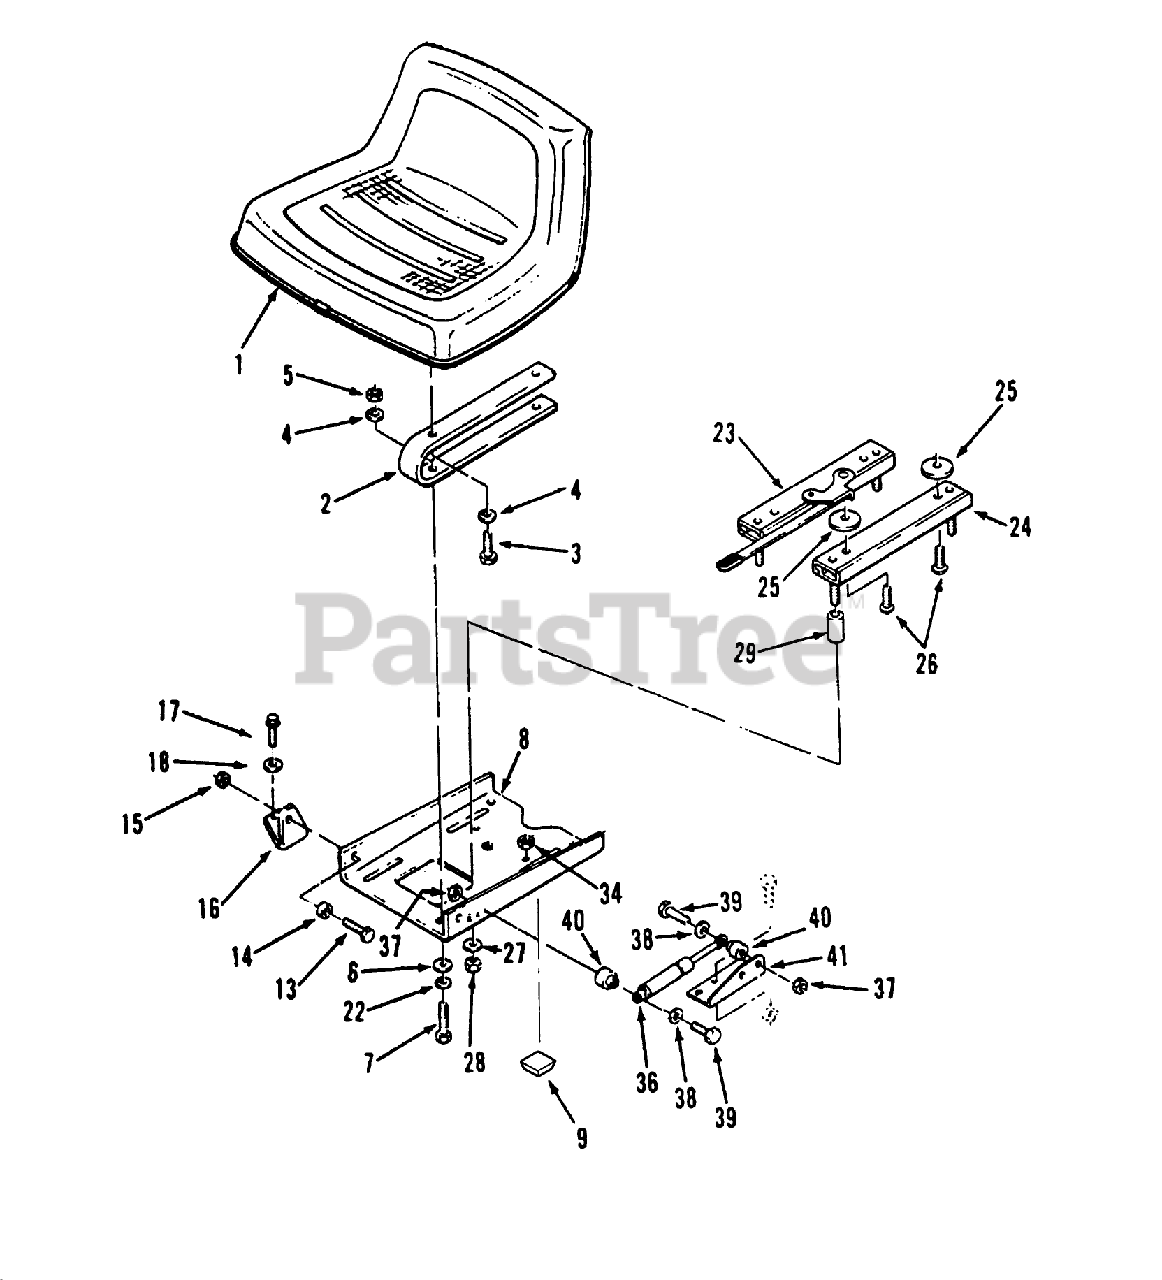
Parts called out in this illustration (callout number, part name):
3	SCREW-HH
4	WASHER-LOCK
5	NUT-LOCK, NI
6	WASHER-PLAIN
7	SCREW-HH
9	BUMPER SJ5514 BLACK
13	SCREW-HH
14	BUSHING
15	NUT-LOCK, NI
16	BRACKET-PIVOT R.H *B (NS)
18	WASHER-PLAIN
22	WASHER-LOCK
25	SPACER-NYLON
27	WASHER-FLAT
28	NUT-HEX
34	NUT-LOCK, NI
36	ASS'Y-GAS SPRING
37	NUT-LOCK, NI
38	WASHER-FLAT
39	SCREW-HH
40	SPACER-SHOULDER-.400
41	BRACKET-CYLINDER *R
